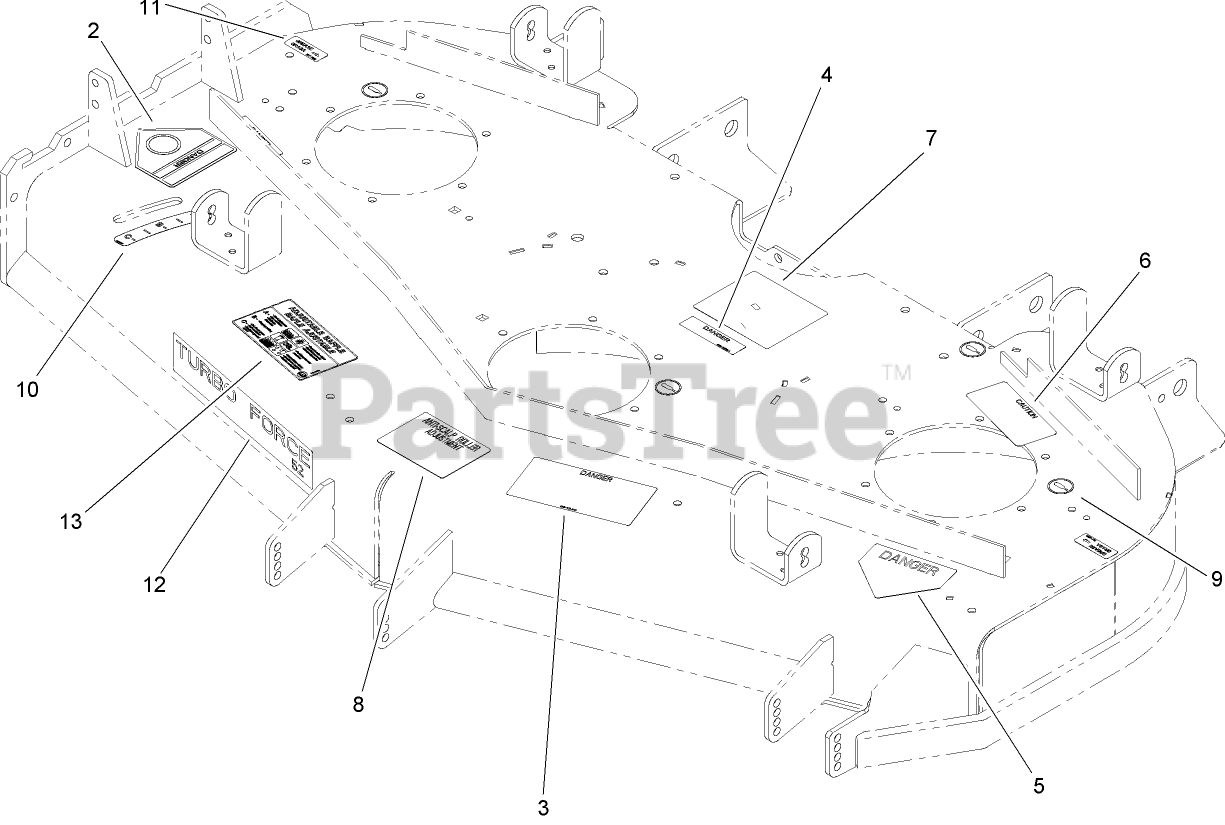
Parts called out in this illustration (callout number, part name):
2	DECAL-DANGER
3	DECAL-DANGER, THROWN OBJECT
4	DECAL-COVER, MISSING
5	DECAL-DANGER
6	DECAL-TORQUE
7	DECAL-ROUTING, BELT
8	DECAL-SCALP, ANTI
9	DECAL-GREASE
10	DECAL-SETTING, BAFFLE
11	Decal-Grease
13	DECAL-ADJUSTMENT, BAFFLE
